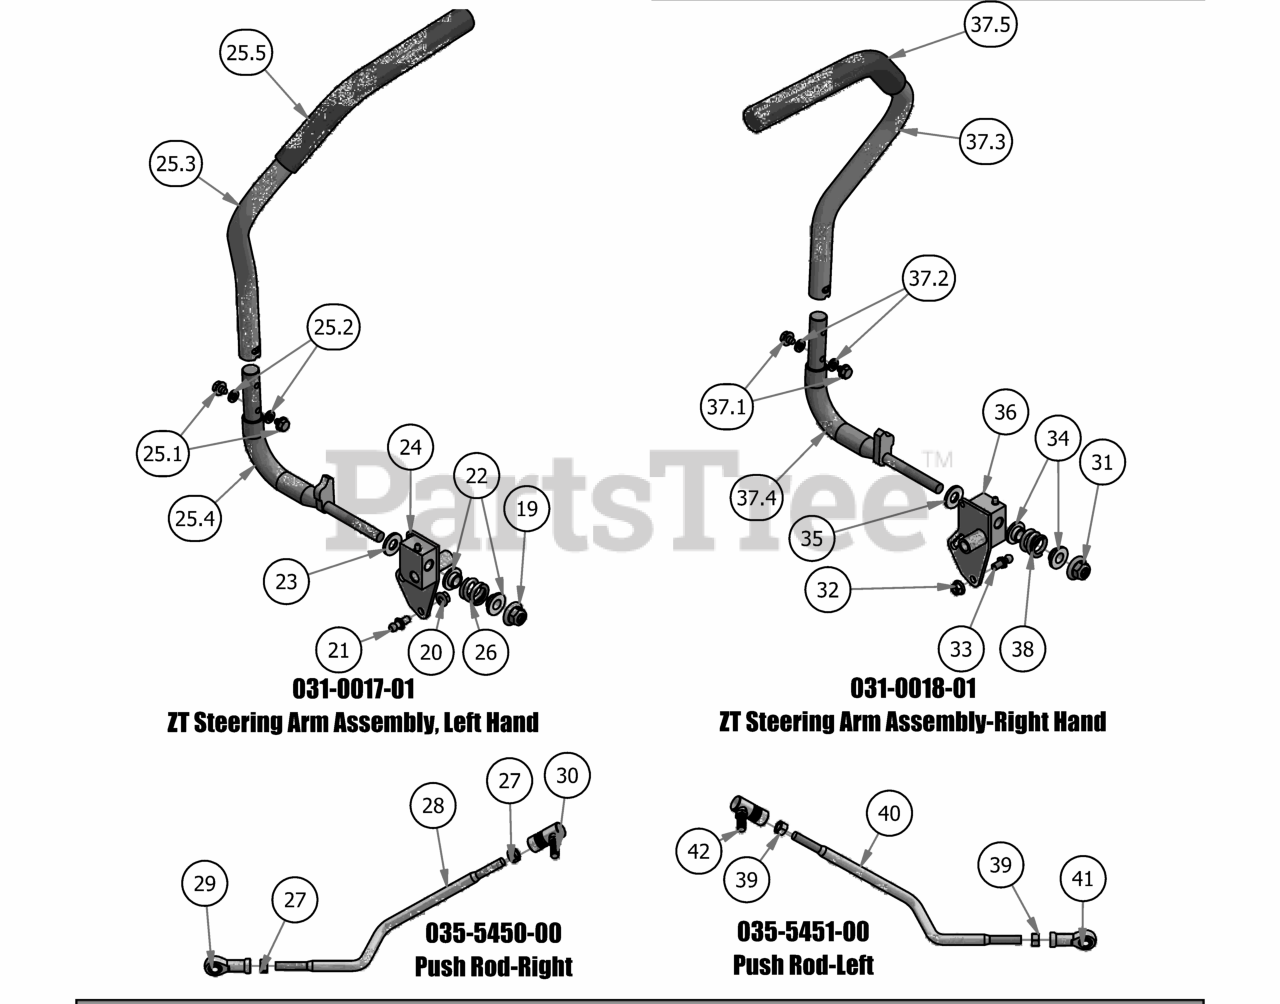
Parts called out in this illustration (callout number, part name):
19	1/2-13 Nylon Flange Nut
20	5/16" Flange Nut
21	10mm Damper Ball Stud-Steering
22	.515 ID Nylon Shoulder Washer
23	.505 Nylon Spacer
24	2017 Drive Lever Housing - Left
25	ZT Steering Arm-Left
25.1	5/16-18 1/2 HWH Bolt-Steering
25.2	5/16" Lock Washer
25.3	ZT Direction Steering Arm (Left)
25.4	Stering Arm Elbow (Left)
25.5	Rubber Grip
26	Drive Lever Spring
27	3/8" Fine Threaded Jam Nut
28	Push Rod - Right
29	Spherical Rod End - Outlaw
30	Quick Release Ball Joint
31	1/2-13 Nylon Flange Nut
32	5/16" Flange Nut
33	10mm Damper Ball Stud-Steering
34	.515 ID Nylon Shoulder Washer
35	.505 Nylon Spacer
36	2017 Drive Lever Housing - Right
37	ZT Steering Arm-Right
37.1	5/16-18 1/2 HWH Bolt-Steering
37.2	5/16" Lock Washer
37.3	ZT Direction Steering Arm (Right)
37.4	Stering Arm Elbow (Right)
37.5	Rubber Grip
38	Drive Lever Spring
39	3/8" Fine Threaded Jam Nut
40	Push Rod - Left
41	Spherical Rod End - Outlaw
42	Quick Release Ball Joint
